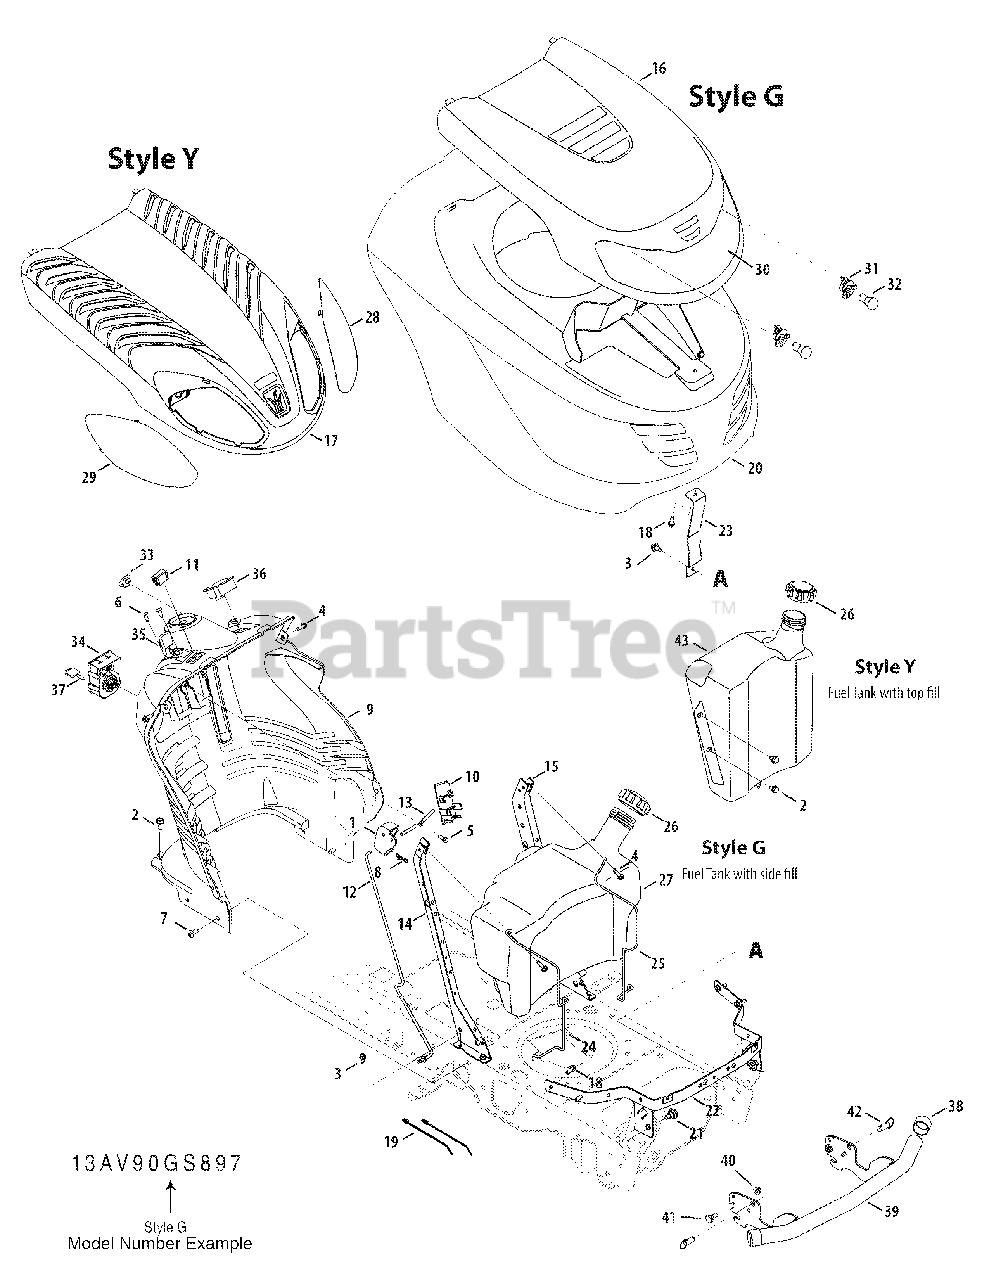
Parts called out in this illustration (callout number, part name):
1	Dash Lever
2	S-Tapp Scr 5/16-18 x .75
3	Hex Wash S-Tapp Scr 1/4-20 x .50
4	Hex TT Screw 1/4-20 x .75
5	Hex Tapp Scr 1/4 x .75" Lg.
6	Torx Mach. AB-Tapp Scr. 1/4-14 x .625 Lg
7	Screw 5/16-18 x .75
8	Bow-Tie Cotter Pin
9	Dash Panel (Man. PTO w/fuel level window)
10	Cruise Cover Y/G Style
11	Light Switch Cap
12	Latch Control Rod
14	RH Dash Support Plate
15	LH Dash Support Plate
16	Upper "G" Style Hood
17	Upper "Y" Style Hood
18	Screw, Bos, 1/4 Dia. x .75
20	G Style Hood (w/side fill fuel tank)
21	Shoulder Screw .43 x .29, 5/16-18
22	Hood Pivot Bracket
23	Hood Support Bracket
24	Tank Support Rod RH
25	Tank Support Rod LH
26	Cap-Fuel
27	Fuel Tank 2.75 Gal. (side fill)
28	Lens LH - Style "Y"
29	Lens RH - Style "Y"
30	Lens (Style G)
30	Reflector Label
31	Socket
32	Miniature Lamp 12V Socket Type
34	Key Switch Module
35	Throttle/Choke Cont. Cable 25" Lg.
36	Ammeter
37	Ignition Key w/Plastic Cover
40	Hex Lock-Nut 3/8-16 Gr.B
41	Shoulder Scr. .498 x .340: 3/8-16
42	Quick Pin 1/2" dia. x 0.50
43	Y Style Hood (w/top fill fuel tank)
